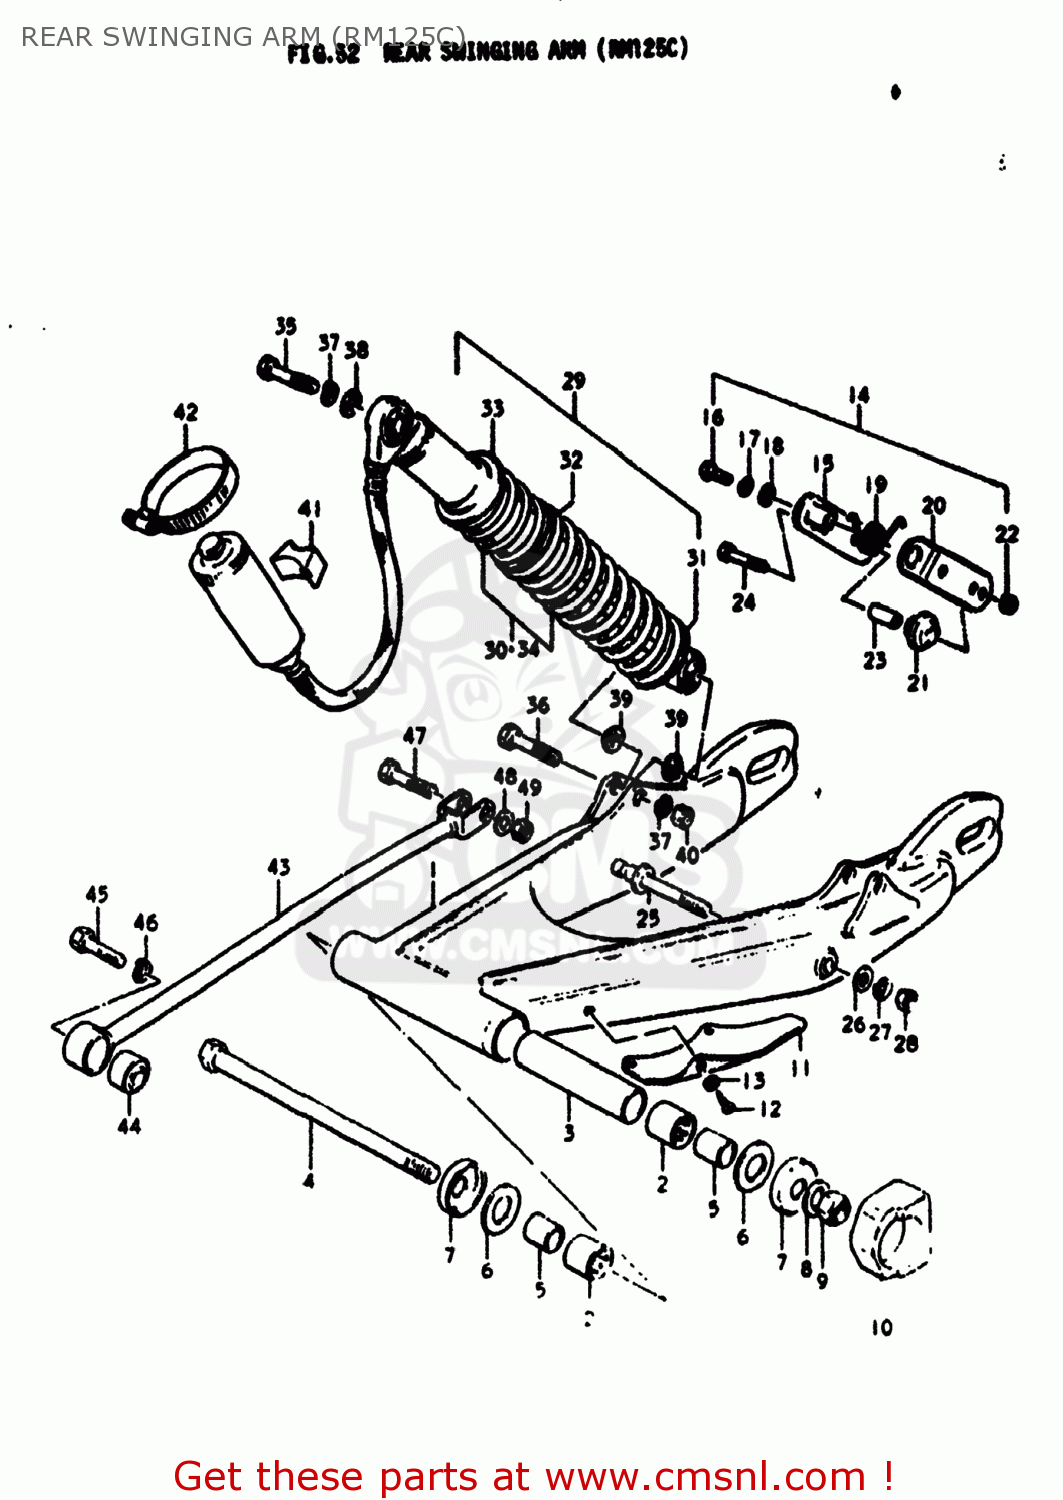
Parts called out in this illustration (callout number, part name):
1	SWING ARM ASSEMBLY,REAR
2	ROLLER BEARING (17X24X2
3	SPACER,REAR SWING ARM PIVOT
4	SHAFT,REAR SWING ARM
5	SPACER,RR SWGARM PIVOT
6	WASHER
7	COVER,REAR SWING ARM DUST
8	WASHER
9	NUT 12MM
10	BUFFER,CHAIN TOUCH DEFENSE
11	BUFFER,CHAIN TOUCH DEFLECTOR
12	SCREW
13	WASHER
15	TENSIONER,CHAIN
16	BOLT
17	LOCK WASHER
18	WASHER
19	SPRING
20	PLATE,CHAIN TENSIONER
21	RUBBER,CHAIN GUARD
22	NUT 6MM
23	SPACER(6.5X10.5X22.5)
24	BOLT
25	HOLDER,CABLE TENSIONER
26	WASHER
27	LOCK WASHER
28	NUT
29	ABSORBER ASSEMBLY,REAR SHOCK
32	SPRING
33	GUIDE,SPRING
35	BOLT 10X40
36	BOLT(10X48)
37	LOCK WASHER
38	WASHER
39	WASHER
40	NUT
41	CUSHION,RR SHOCK ABSORBER
42	CLAMP
43	LINK,REAR TORQUE
44	BUSH
45	BOLT 10X40
46	LOCK WASHER
47	BOLT 10X40
48	WASHER
49	NUT
